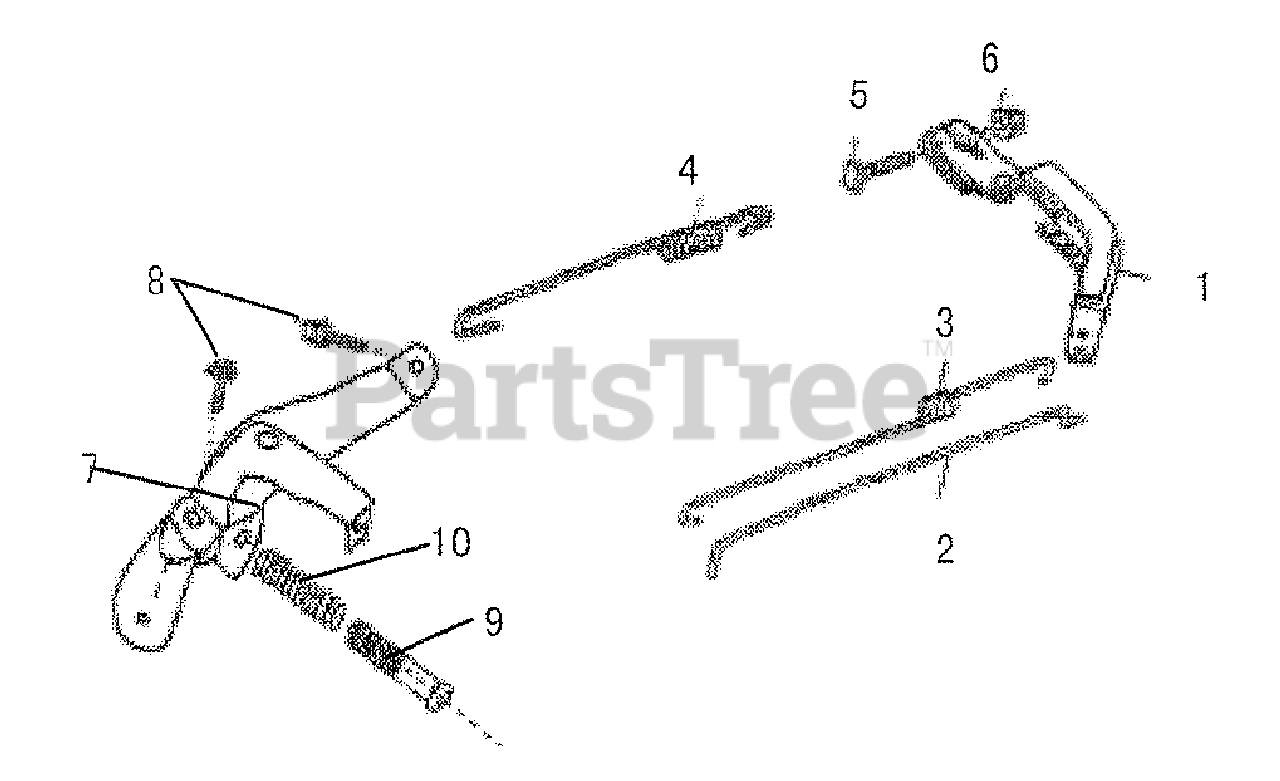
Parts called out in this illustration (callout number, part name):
1	ARM, GOVERNOR
2	ROD, GOVERNOR
3	SPRING, CONTROL ADJ
4	SPRING, THROTTLE RETURN
5	BOLT, GOV. ARM(T) 6X21
6	NUT, FLANGE 6MM
7	BASE COMP., CONTROL
8	BOLT, FLANGE, 6X12
